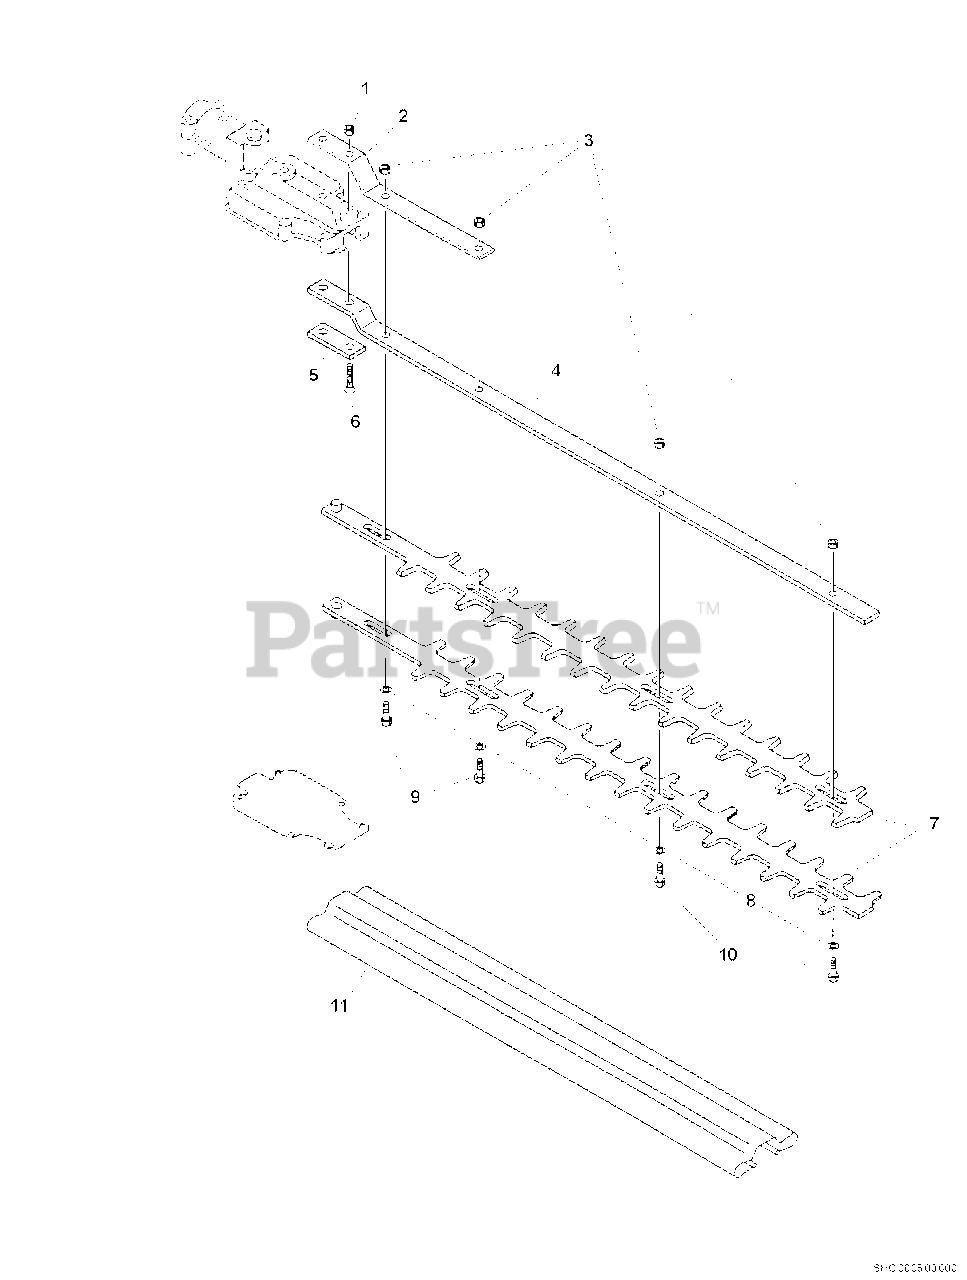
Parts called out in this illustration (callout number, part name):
1	LOCKNUT - 6
3	LOCKNUT - 6
4	SUPPORT, BLADE - 20" (50cm)
6	SCREW - 6X35
7	BLADE - 20" (50cm)
8	WASHER - 6
10	BOLT - 6
11	COVER, BLADE
